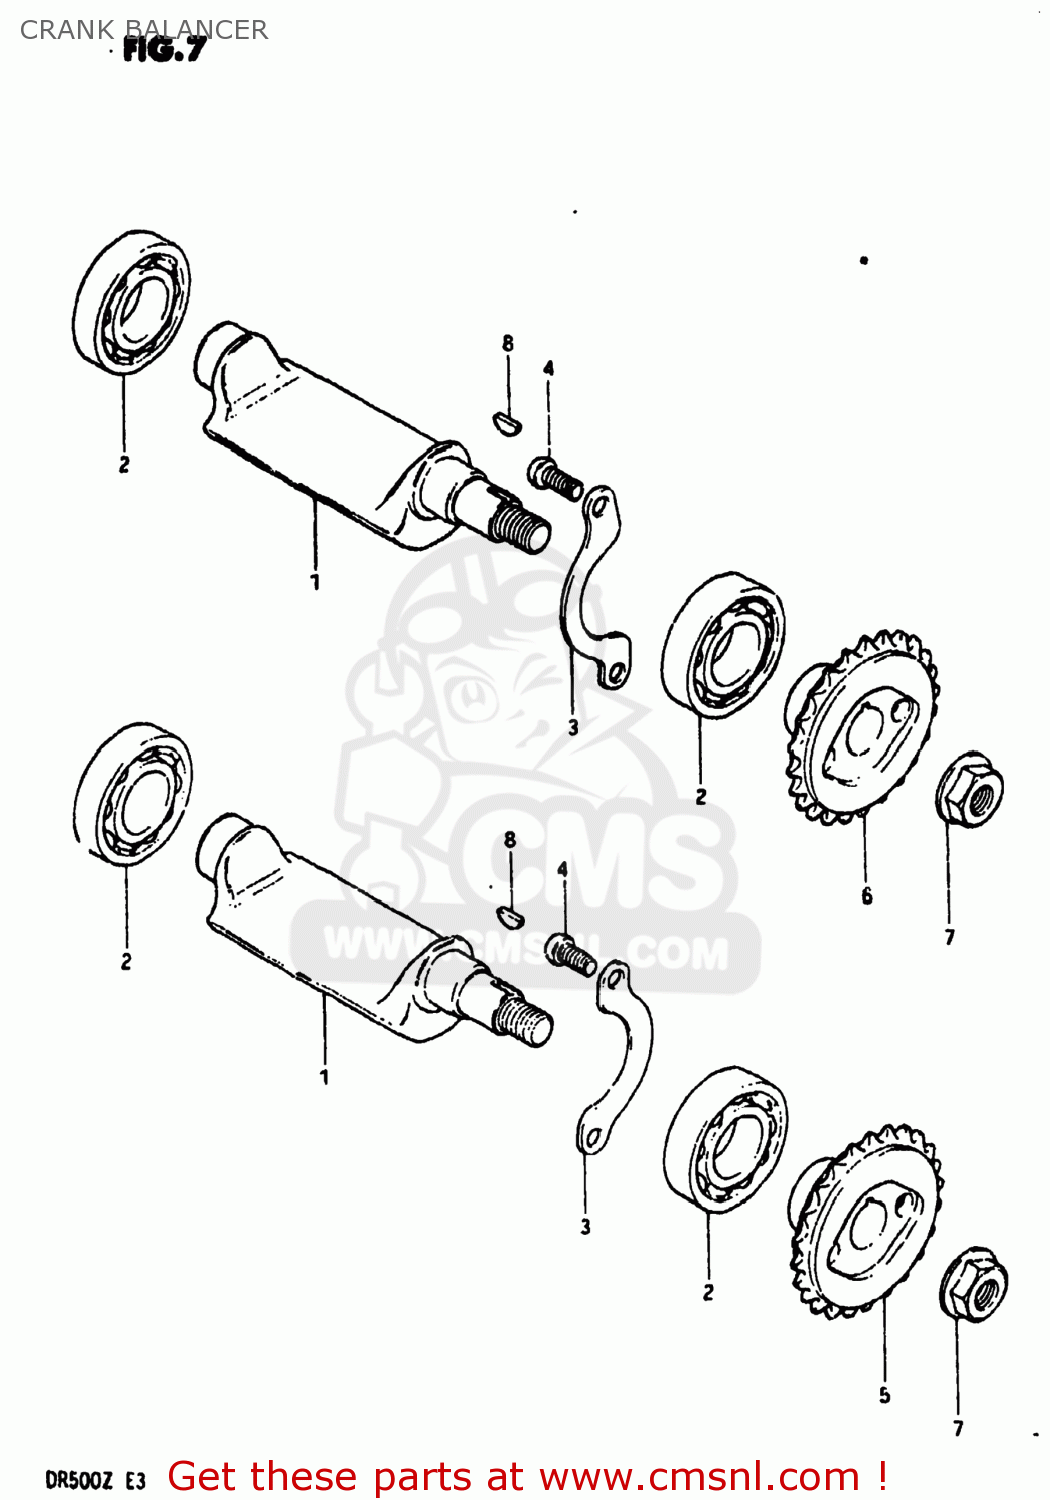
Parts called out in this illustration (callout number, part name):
1	BALANCER,CRANKSHAFT
2	BEARING
3	RETAINER,CRANK BAL BEARING
4	SCREW 6X12
5	SPROCKET,BALANCER DRIVE
6	SPROCKET,BALANCER DRIVE
7	NUT
8	KEY
